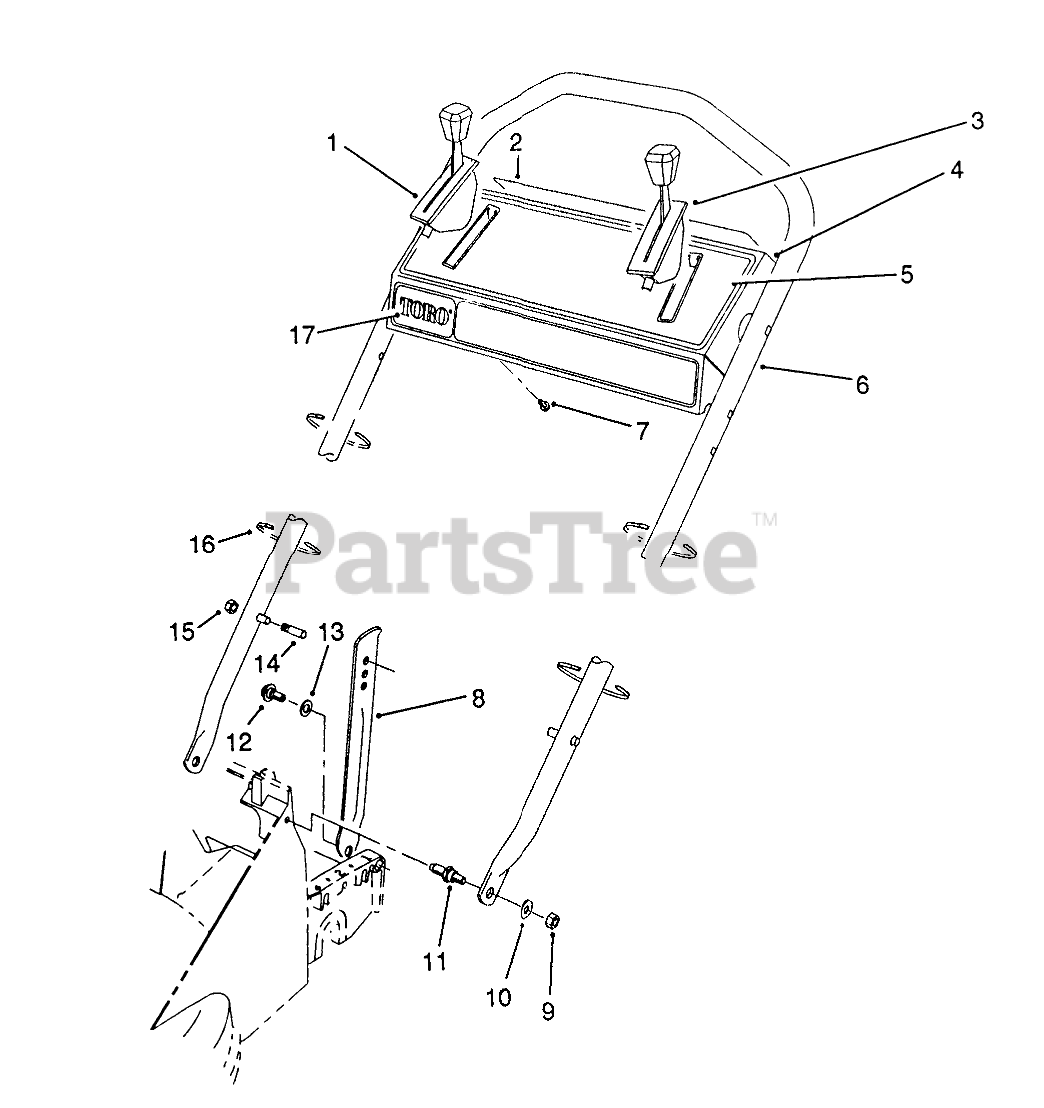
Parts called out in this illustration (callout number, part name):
1	Control-Ground Speed
2	DECAL-PANEL, DANGER
3	ControI-Throttle Bend Type #2 Sheath Lg. 44-3/4" Wire Lg. 2-1/2"
4	Control Panel Assembly (Incl. Ref. #2, 5 & 17)
5	DECAL - INSTRUCTION
6	HANDLE
7	SCREW-HWHTF
8	HANDLE LATCH
9	NUT-LOCK, NI
10	WASHER-PLAIN
11	SCREW - SHOULDER STUD
12	SCREW-SHOULDER
13	NYLON WASHER
14	HANDLE PIN
15	NUT-LOCK, NI
16	TIE-CABLE
17	DECAL - TORO PANEL
